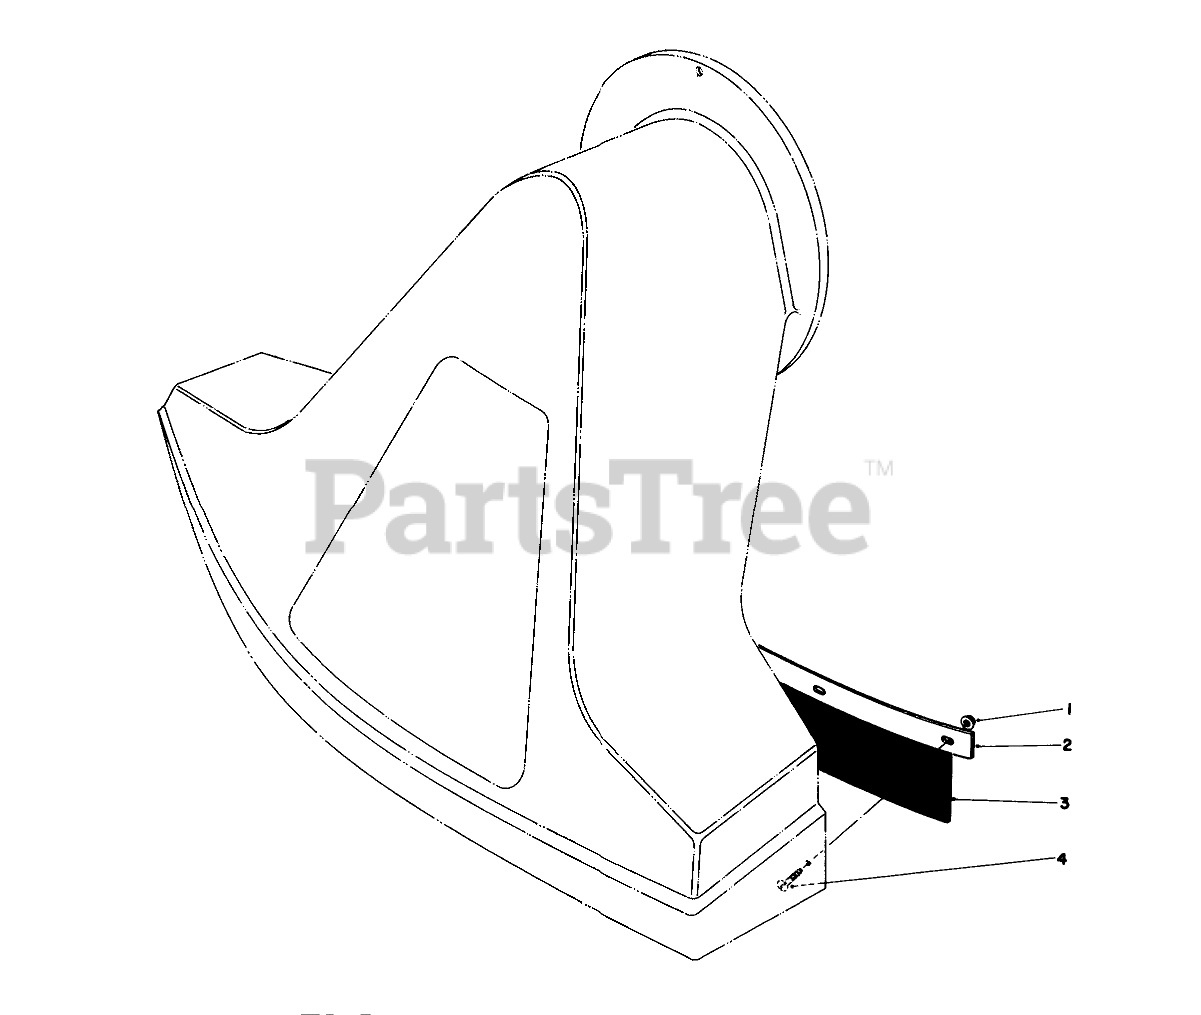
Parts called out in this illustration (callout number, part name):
1	NUT-LOCK, FLANGE
2	Clamp-Flap
3	FLAP-RUBBER
4	10-24 X 5/8 PAN HD MS
